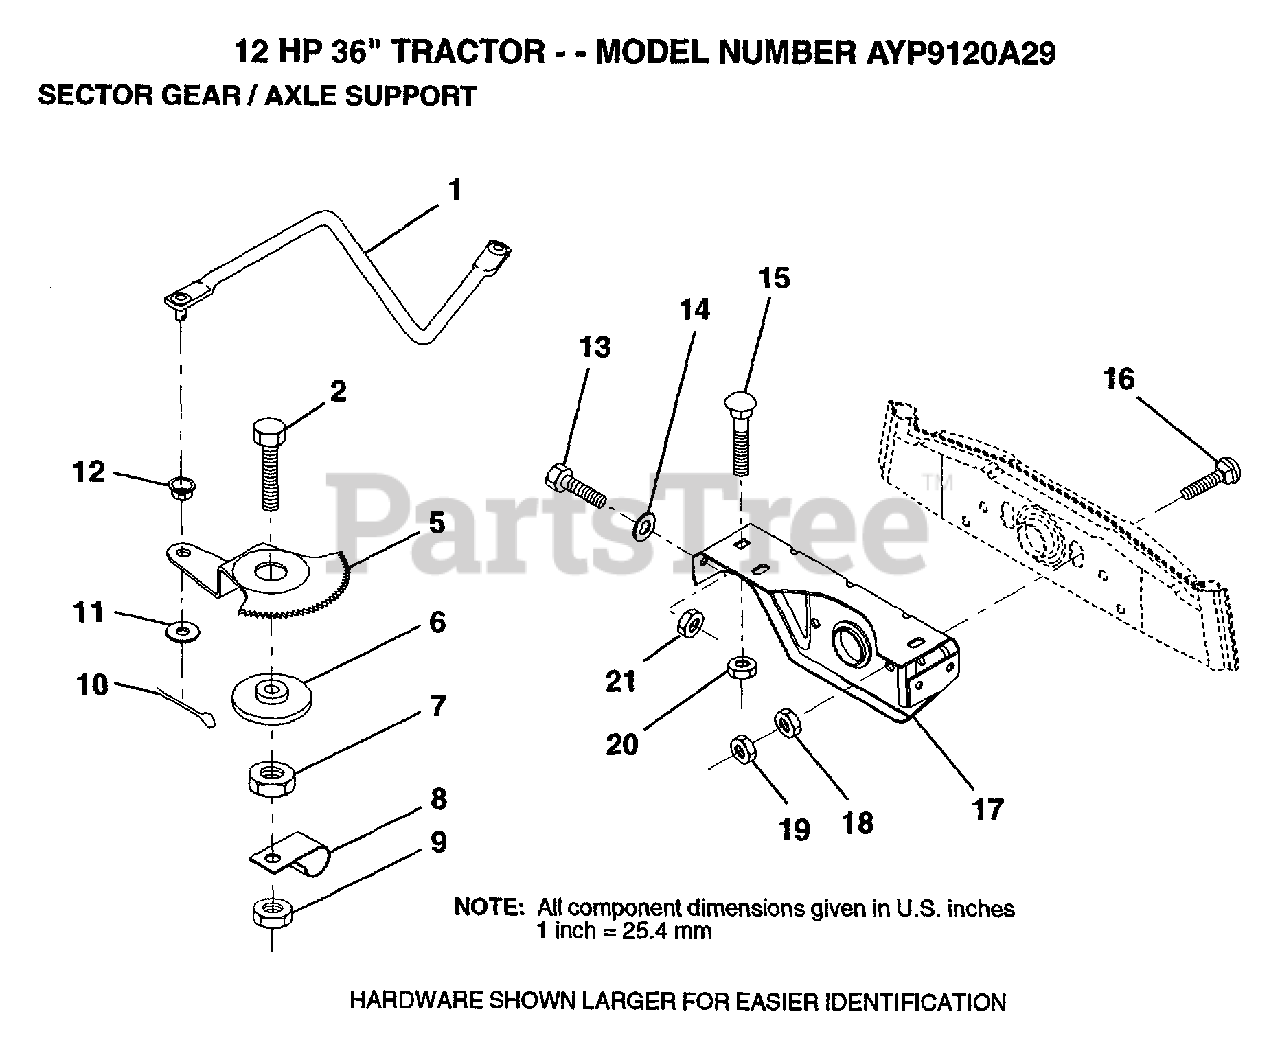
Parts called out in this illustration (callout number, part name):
1	DRAG LINK
2	"BOLT,HEX"
5	GEAR SECTOR
6	BUSHING
7	NUT
8	CLIP INSULATOR
9	NUT LTV
10	COTTER PIN
11	WASHER
12	BUSHING.DRAGLINK
13	BOLT
14	WASHER
15	BOLT
16	BOLT
17	"SUPT,FRT AXLE"
18	NUT.HEX.3/8-16UNC
19	LOCKNUT
